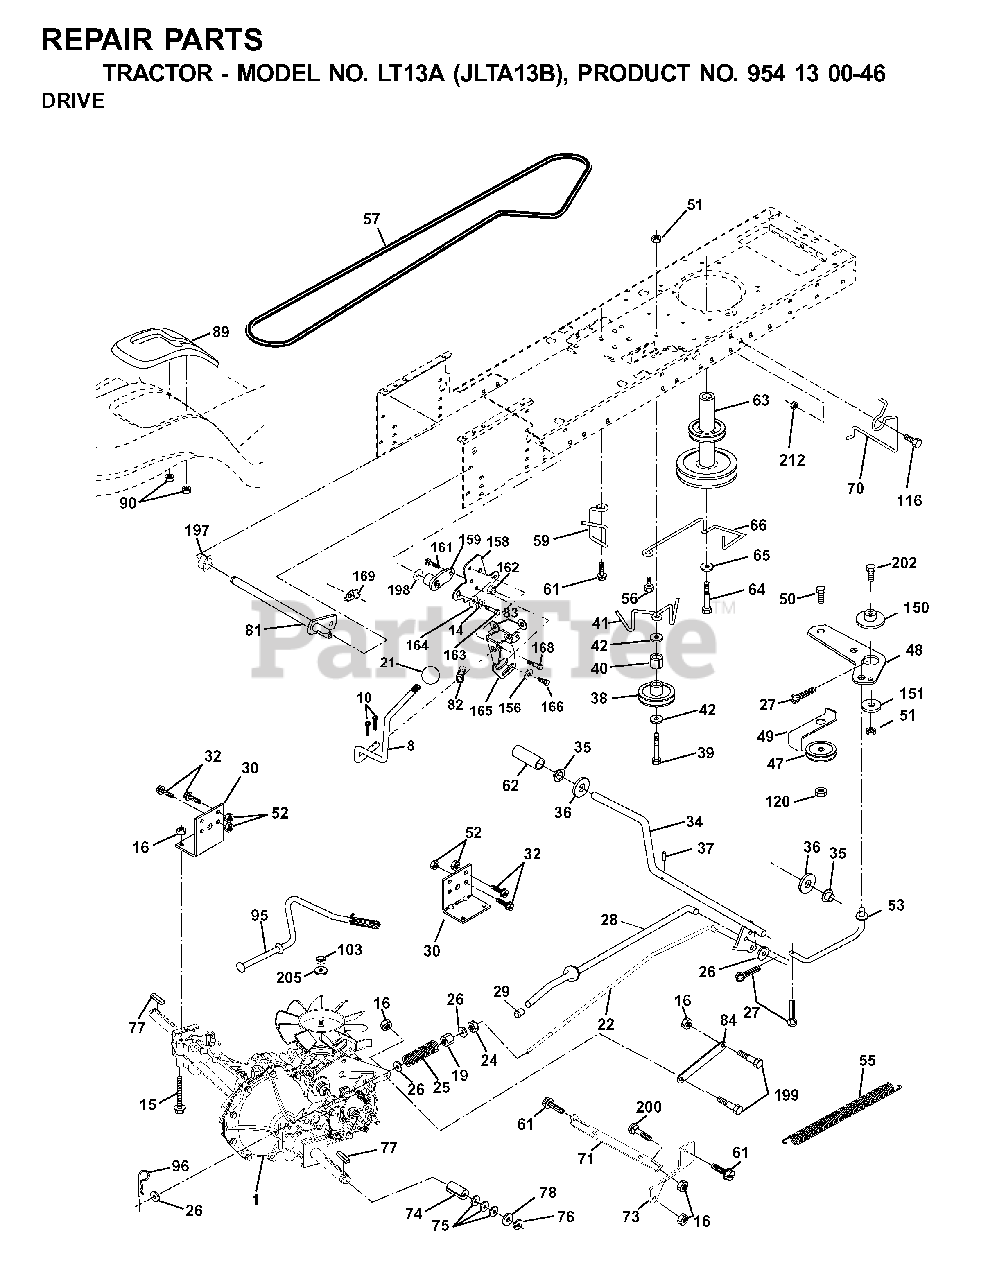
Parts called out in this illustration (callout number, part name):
8	ROD SHIFT FENDER ADJUST STLT
10	PIN COTTER
14	LOCKWASHER
15	BOLT HEX 5/16-18 GR 5
16	NUT.71038.31-18.HEX.NYLOCK
19	NUT
21	KNOB.DUCKHEAD.1/2
22	ROD BRAKE HYDRO
24	NUT
25	SPRING ROD LT
27	COTTER PIN
28	ROD, PARKING BRAKE
29	PLUNGER CAP
30	BRKT, MOUNT TRNSAXLE
32	BOLT
34	SHAFT, FOOT PEDAL
35	BEARING.NYLON
36	WASHER LT
37	DRIVE PIN
38	PULLEY.FLAT
39	BOLT
40	SPACER, SPLIT
41	KEEPER, BELT IDLER
42	WASHER
47	IDLER PULLEY
48	BELLCRANK, CLUTCH
49	RETAIN BELT
50	BOLT
51	LOCKNUT
52	LOCKNUT
53	LINK, CLUTCH LT
55	SPRING, RETURN LT
57	DRIVE BELT, LTH & YTH TRACTORS
59	KEEPER, BELT CENTER
61	SCREW 3/8-16X3/4
62	PEDAL COVER T
63	ENGINE PULLEY
64	BOLT
65	LOCKWASHER
66	KEEPER BELT ENGINE
70	KEEPER BELT ENG
71	STRAP TORQUE LH HYDRO
73	STRAP TORQUE RH HYDRO
74	SPACER AXLE
76	E-RING LT
77	SQUARE KEY
81	SHAFT ASM CROSS TAPERED
82	SHIFT SPRING
83	WASHER
95	CONTROL ASM. BYPASS HYDRO
96	RETAINER M
103	NUT.HEX.1/2-20
116	BOLT D
120	NUT LOCK FLG 3/8-16 UNC
150	SPACER, RETAINER
151	WASHER 12/32X2X10GA
156	WASHER.SRRTD.5/16
158	BRACKET
159	HUB
161	BOLT
162	NUT.CROWNLOCK.1/4
165	RP BRACKET
168	BOLT.SHOULDER.5/16-18X
169	PLATE.FASTENING.CROSS.SHAFT
197	NYLINER SNAP 5/8" ID
198	WASHER.NYL.7/8IDX.105"HYD CR
199	BOLT SHOULDER 5/16-18 UNC
200	BOLT
202	BOLT.3/8-16X1.50
205	WASHER
212	NUT
